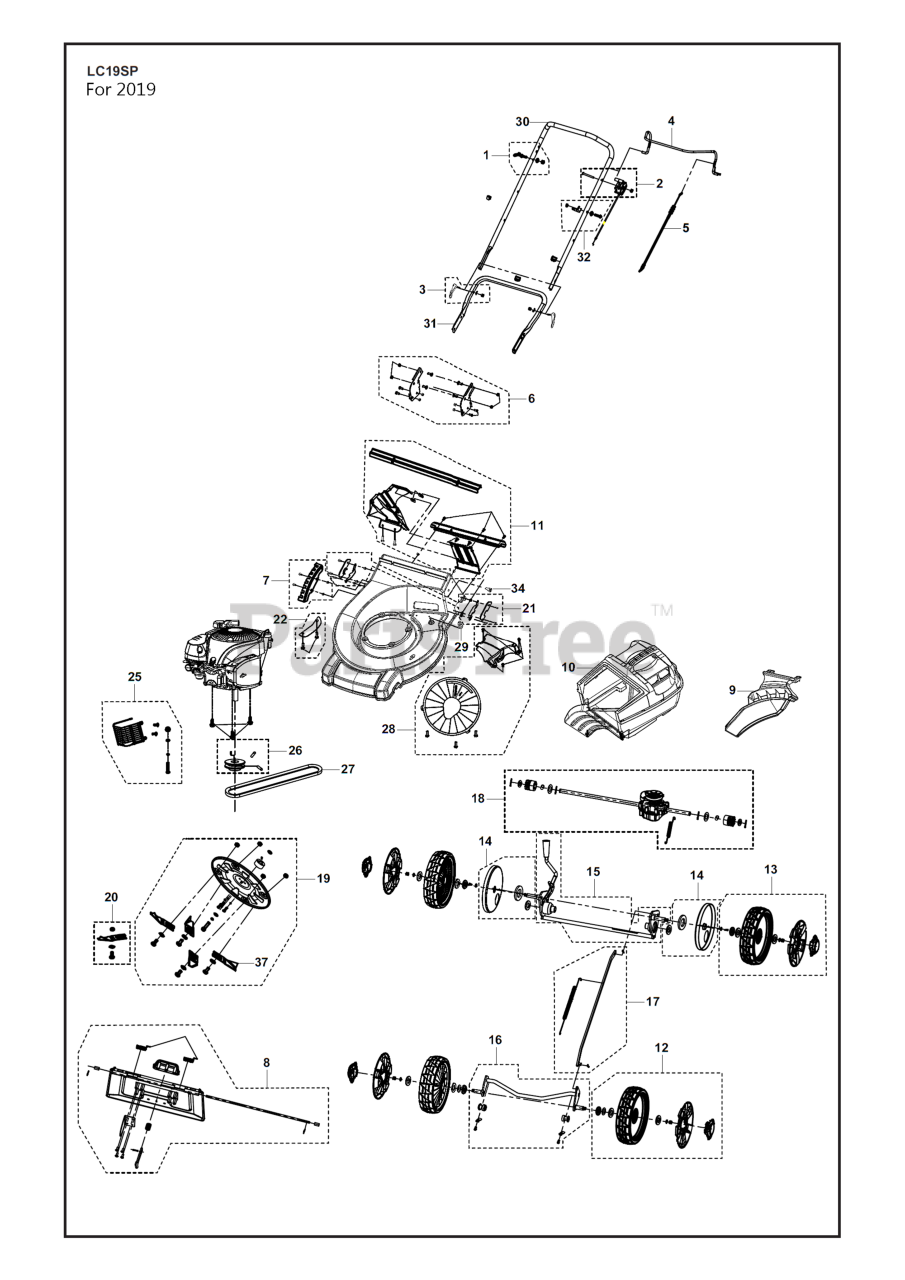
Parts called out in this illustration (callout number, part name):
5	VALUE.OIL.DRAIN
8	CAP.FL.R.3'N/CARB.H.CROWN.498
10	LOCKNUT M8
11	WASHER BRB 8.4X17
